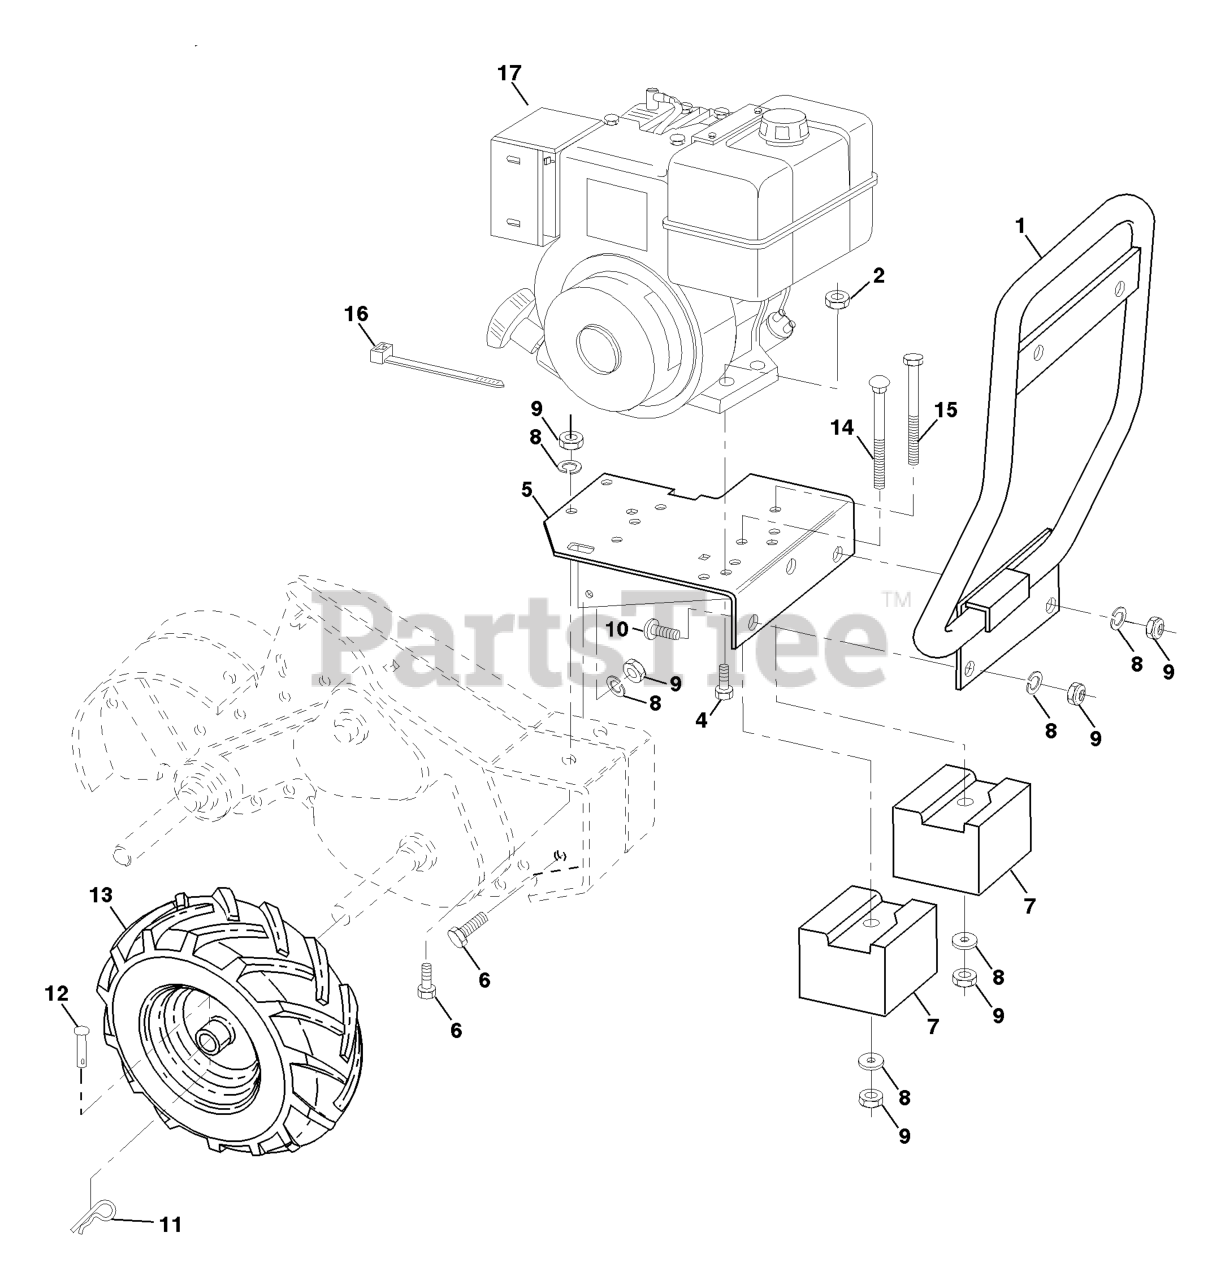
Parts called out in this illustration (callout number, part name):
2	NUT
4	BOLT, HEX 5/16-18X1-3/4
5	ENGINE BRACKET
6	BOLT
7	COUNTER WEIGHT RH
8	WASHER, LOCK 3/8
9	NUT.HEX.3/8-16UNC
10	BOLT D
11	SPRING TI
13	TIRE.16X4-8.CHEVRON.TILLER
13	RIM
13	VALVE STEM LT
14	Bolt, Carriage 3/8-16 x 4-1/2
15	BOLT, HEX 3/8-16X4-1/2
17	Engine
